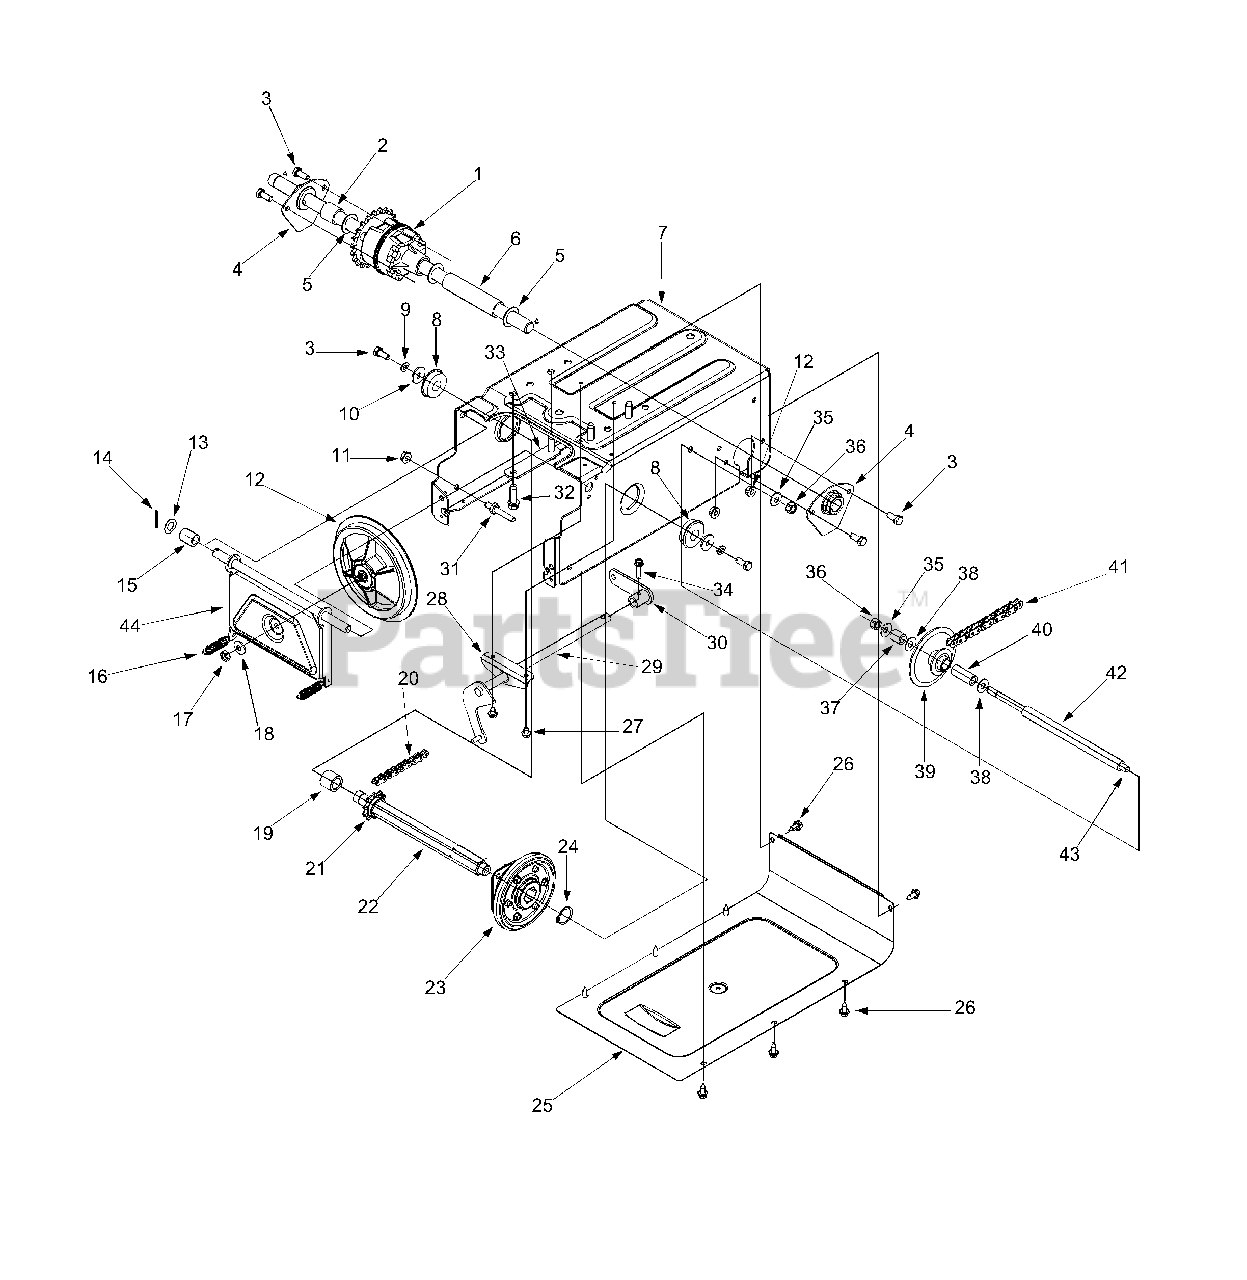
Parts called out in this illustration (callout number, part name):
1	Transmission Assembly
2	Spacer .782 ID x 1.0 OD
3	Hex Cap Screw 5/16-18 x .75
4	Axle Bracket Assembly
5	Flat Washer .793 ID x 1.24 OD
6	Spacer .782 ID x 1.0 OD
9	Lock Washer 5/16
10	Flat Washer .312 ID x .934 OD
11	Flange Lock Nut 5/16-18
12	Friction Disc Assembly
13	Flat Washer .53 ID x .93 OD
14	Cotter Pin
15	Spacer .508 ID x .75 OD
16	Extension Spring .48 OD x 2.03
17	Jam Nut 3/8-24
18	Spring Washer .401 ID x .870 OD
19	Spacer .675 ID x 1.0 OD
20	Chain #41 36 Links
21	Sprocket 10T #41
22	Hex Shaft .875
23	Friction Wheel Assembly
24	Snap Ring 1.0 Dia.
27	Hex Washer Screw 1/4-20 x .375
29	Shift Shaft Assembly
32	Hex Washer Screw 3/8-16 x 1.25
35	Spring Washer .401 ID x .870 OD
36	Hex Nut 3/8-24
37	Spacer .407 ID x .625 OD
38	Flat Washer .375 ID x .870 OD
39	Sprocket Assembly 9T & 22T
40	Sleeve .380 ID x .623 OD x 1.5
41	Chain #420 36L
42	Spacer .407 ID x .625 OD x 7.86
43	Jack Shaft .375 x 11.40
44	Friction Wheel Support Bracket
